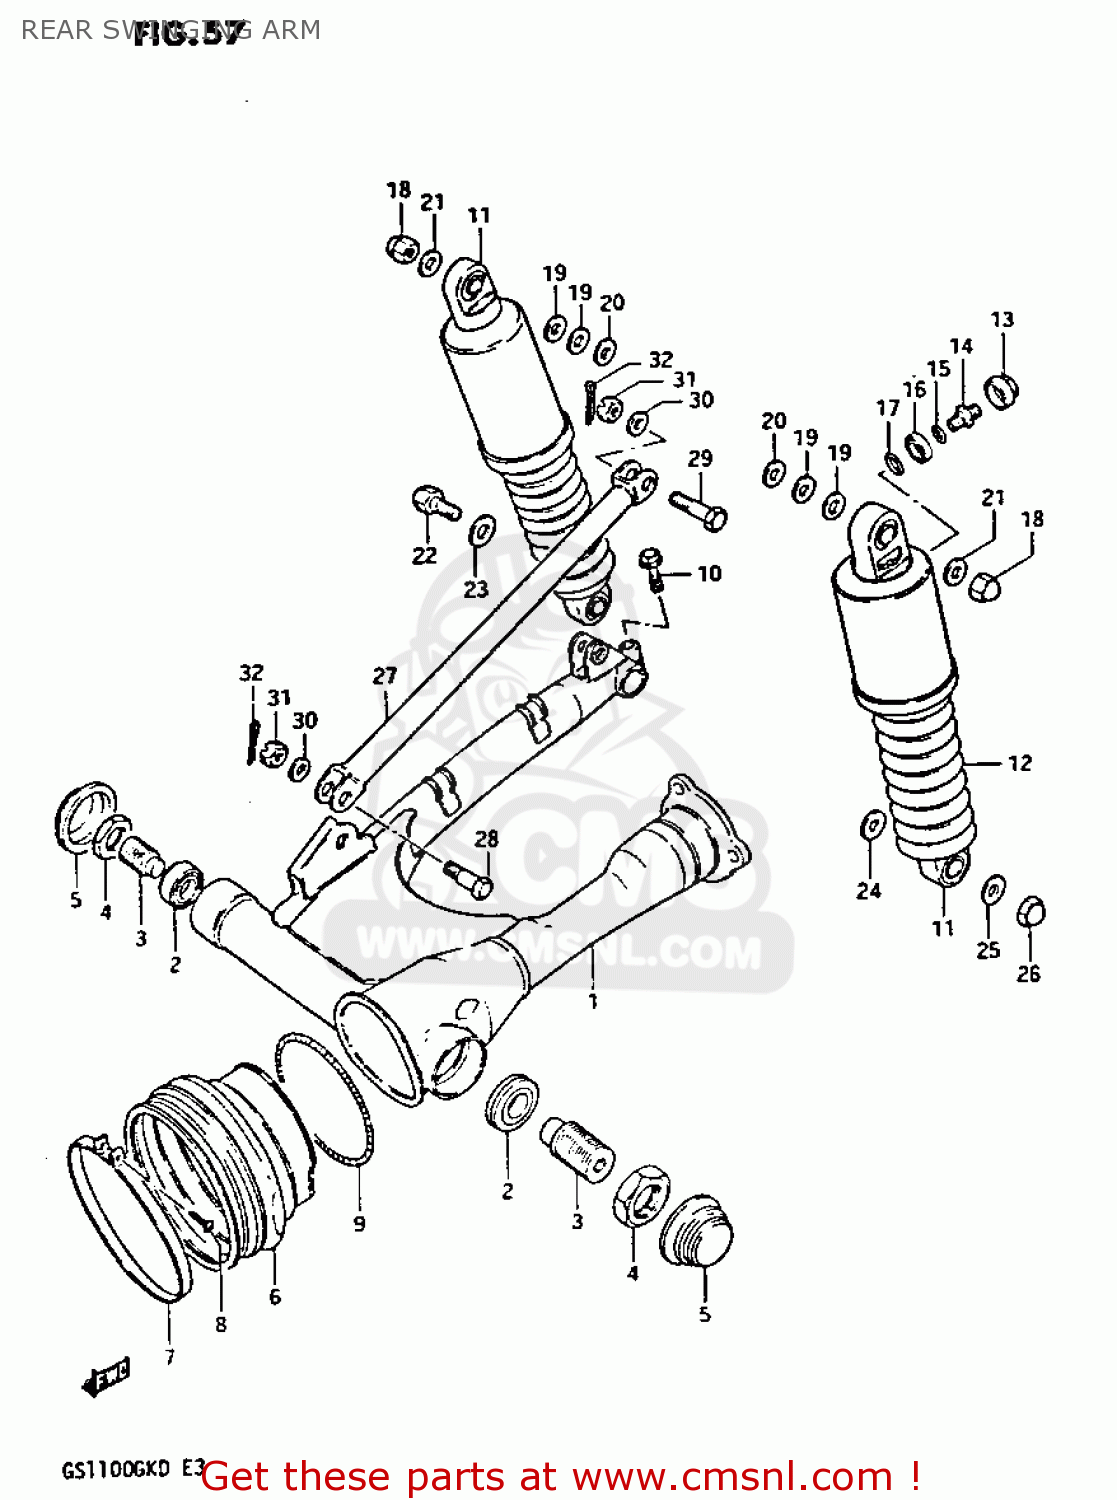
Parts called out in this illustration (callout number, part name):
1	SWING ARM SET,REAR (B
2	BEARING(17X40X13.25)
3	BOLT,REAR SWING ARM PIVOT
4	NUT
5	CAP,REAR SWING ARM PIVOT
6	BOOT,PROPELLER SHAFT
7	CLAMP
8	SCREW 4X25
9	SPRING,PROPELLER SHAFT
10	BOLT
11	ABSORBER ASSEMBLY,REAR SHOCK
12	BOOT,RR SHOCK
13	CAP,VALVE
14	VALVE
15	O-RING
16	SPACER,REAR SHOCK ABSORBER
17	O RING,RR SHOCK
18	NUT
19	WASHER
20	WASHER(15.5X26X2.3)
21	WASHER
22	BOLT 12X33
23	WASHER (12.5X24X1.6)
24	WASHER
25	WASHER
26	NUT
27	LINK,REAR TORQUE
28	BOLT
29	BOLT(10X39)
30	WASHER
31	NUT
32	PIN 20X20
